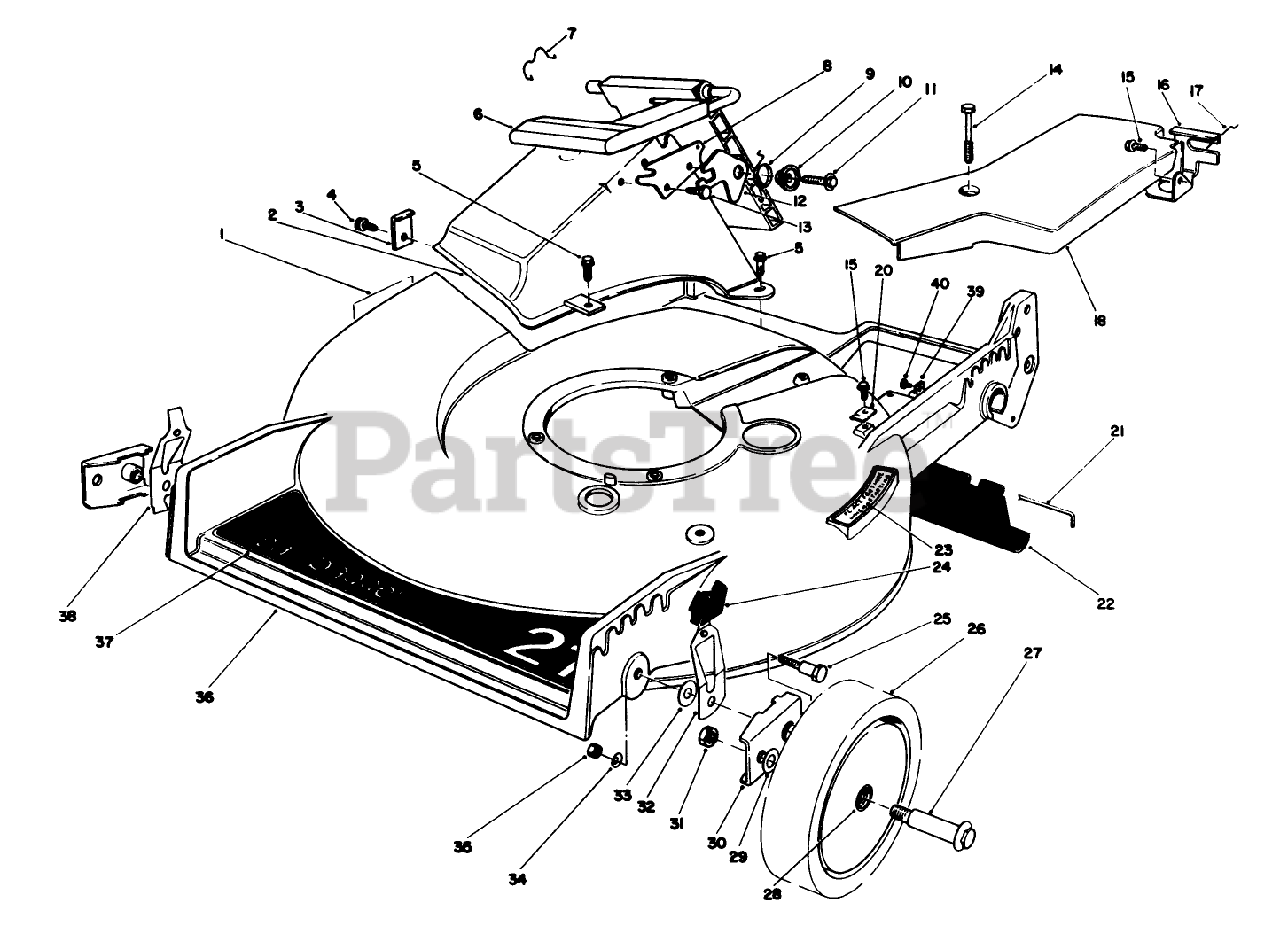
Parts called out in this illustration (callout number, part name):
1	DECAL-DANGER
3	TUNNEL CLIP
4	SCREW
5	SCREW-HWH
7	DOOR RET SPRING
8	DOOR LATCH PLATE
9	Spring-Torsion
10	DOOR SPACER
11	SCREW-HWH
12	SAFETY LATCH
13	SCREW-PLASTITE
14	SCREW-HWH
15	SCREW-HWHTF
17	RETAINER-CABLE
20	CLAMP-CABLE
21	ROD-SHIELD
23	STEP PAD DECAL
24	KNOB-ARM
25	PIVOT SCREW
27	BOLT-WHEEL
28	BUSHING
29	WASHER
30	HP PIVOT ARM ASM
33	WASHER-PIVOT
34	WASHER-BELLEVILLE
35	NUT-LOCK, NI
39	CLAMP-CABLE
40	SCREW
